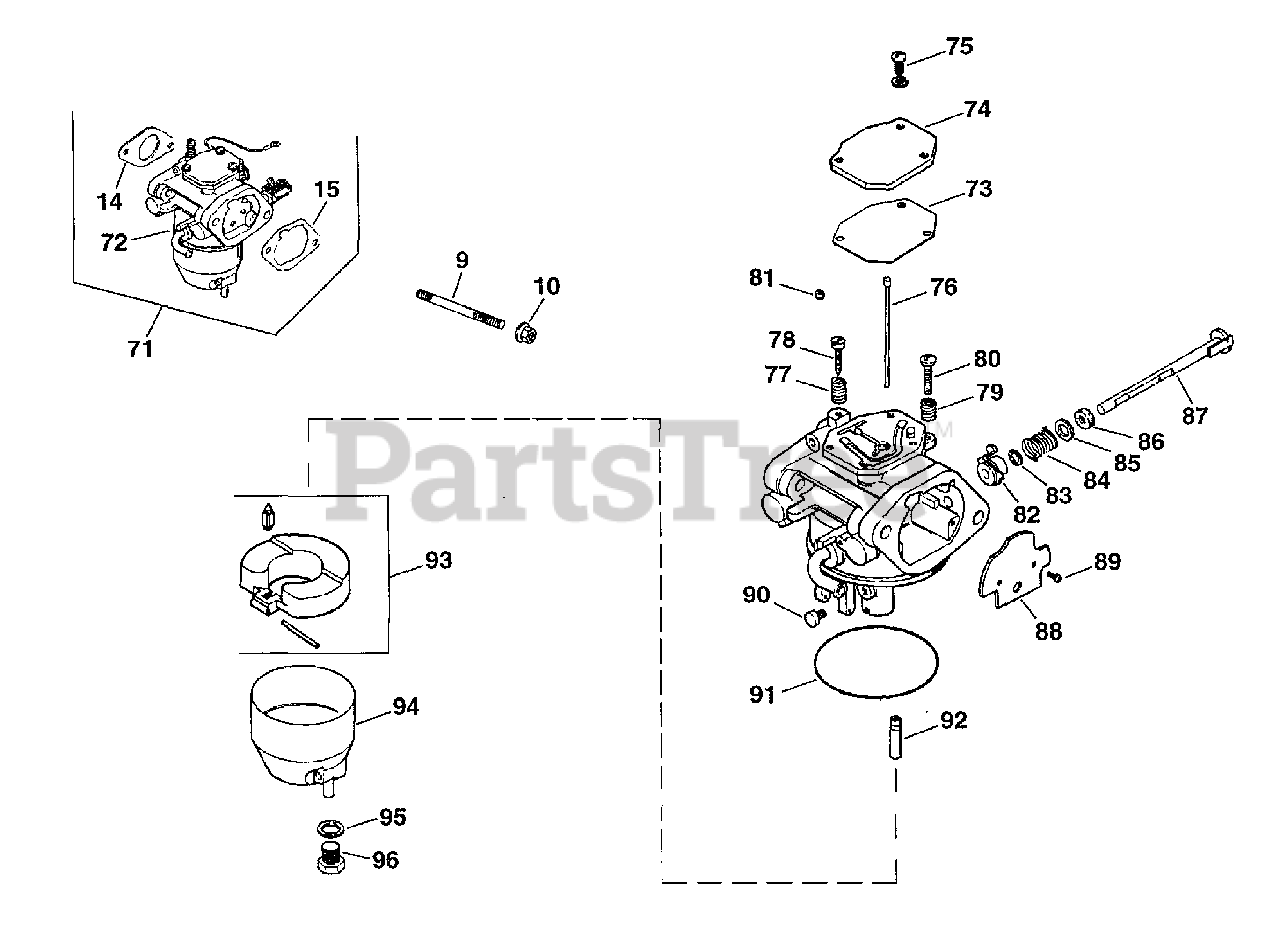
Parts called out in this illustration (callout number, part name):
9	Stud, M6x1.0x128
10	NUT - USE M-641060
14	GASKET, CARBURETOR
15	GASKET, AIR CLEANER BASE
71	CARBURETOR - USE 24 853 16
71	KIT, CARBURETOR W/GASKET
72	Carburetor assembly
72	KIT, CARBURETOR W/GASKETS USE 24 853 16
73	KIT - USE 24 757 20
74	COVER, PASSAGE - DISCONTINUED
75	SCREW DISCONTINUED
76	JET, SLOW - DISCONTINUED
77	KIT - USE 24 757 18
78	SCREW, IDLE ADJUST - USE 24 757 18
79	SPRING, THROTTLE - DISC
80	KIT - USE 24 757 18
81	JET, AIR BLEED - DISC.
83	RING, CHOKE LEVER-USE 24 757 19-S
85	COLLAR, CHOKE-USE 24 757 19-S
86	WASHER-USE 24 757 19-S
87	SHAFT, CHOKE-USE 24 757 19-S
88	PLATE - USE 24 146 13
88	PLATE, CHOKE-USE 24 757 19-S
89	SCREW - DISCONTINUED
90	JET, MAIN - DISCONTINUED
91	KIT - USE 24 757 20
92	NOZZLE DISCONTINUED
93	KIT - USE 24 757 18
94	CHAMBER, FLOAT
95	DISC. SEE PARTS BULLETIN
96	SCREW, CHAMBER SET - DISC.
